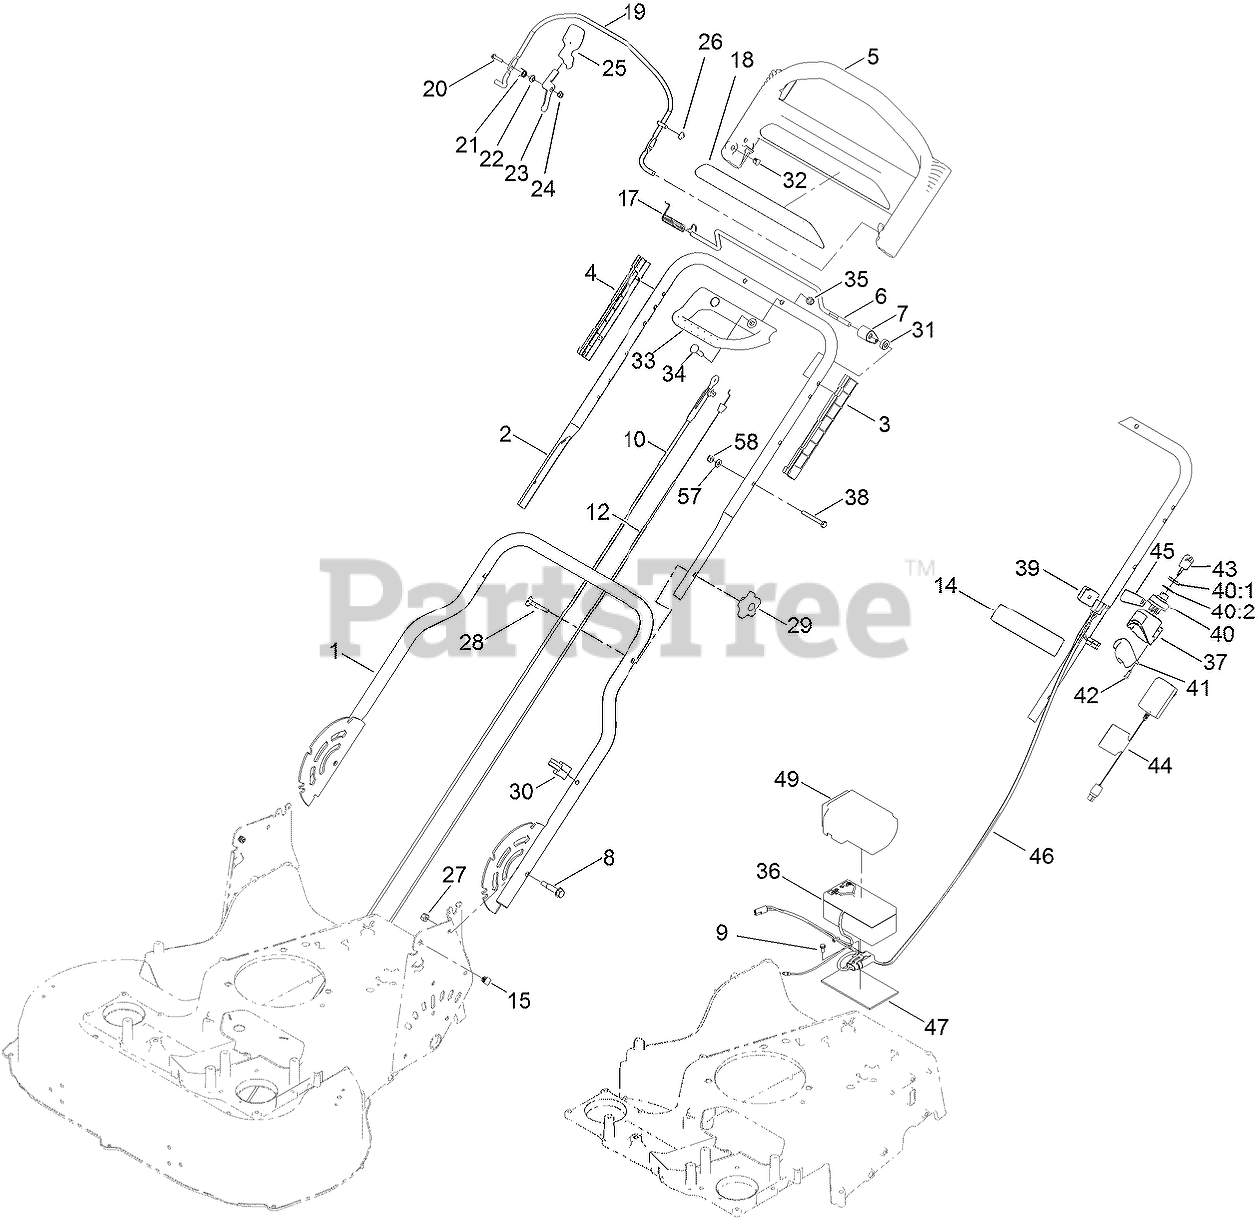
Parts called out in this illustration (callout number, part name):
1	HANDLE-LOWER
2	HANDLE-UPPER
3	GUIDE-LH
4	GUIDE-RH
5	HANDLE-CONTROL
6	BAR-CONTROL, TRACTION
7	LEVER-TRACTION
8	BOLT-SHOULDER, HHF
9	SCREW-TAPTITE
10	CABLE-BRAKE
12	CABLE-TRACTION
14	DECAL-BATTERY CHARGING
15	PLUG-SQUARE
17	SPRING-TORSION
19	BAIL-BRAKE
20	SCREW-HWH
21	SPRING-TORSION
22	SPACER
24	NUT-LOCK, FLANGE
26	NUT-SPEED
27	NUT-LOCK, NI
28	SCREW-HANDLE
29	KNOB-HANDLE
30	GUIDE-CABLE
31	SPACER
32	PLUG-DOME
33	HANDLE-ASSIST, TRACTION
34	BOLT-CARRIAGE
35	NUT-ACORN
36	BATTERY-WET
37	HOUSING-SWITCH, KEY
38	SCREW-HH
39	ANCHOR-CABLE, UPPER
40	SWITCH-STARTER
40:1	NUT-HH
40:2	WASHER-LOCK
41	COVER-SWTCH
42	SCREW-PPH
44	CHARGER, BATTERY (12V)
45	DECAL-SWITCH, IGNITION
46	HARNESS-WIRE
47	FOAM-BATTERY
49	COVER-BATTERY
57	WASHER-FLAT
58	NUT-LOCK, NI
